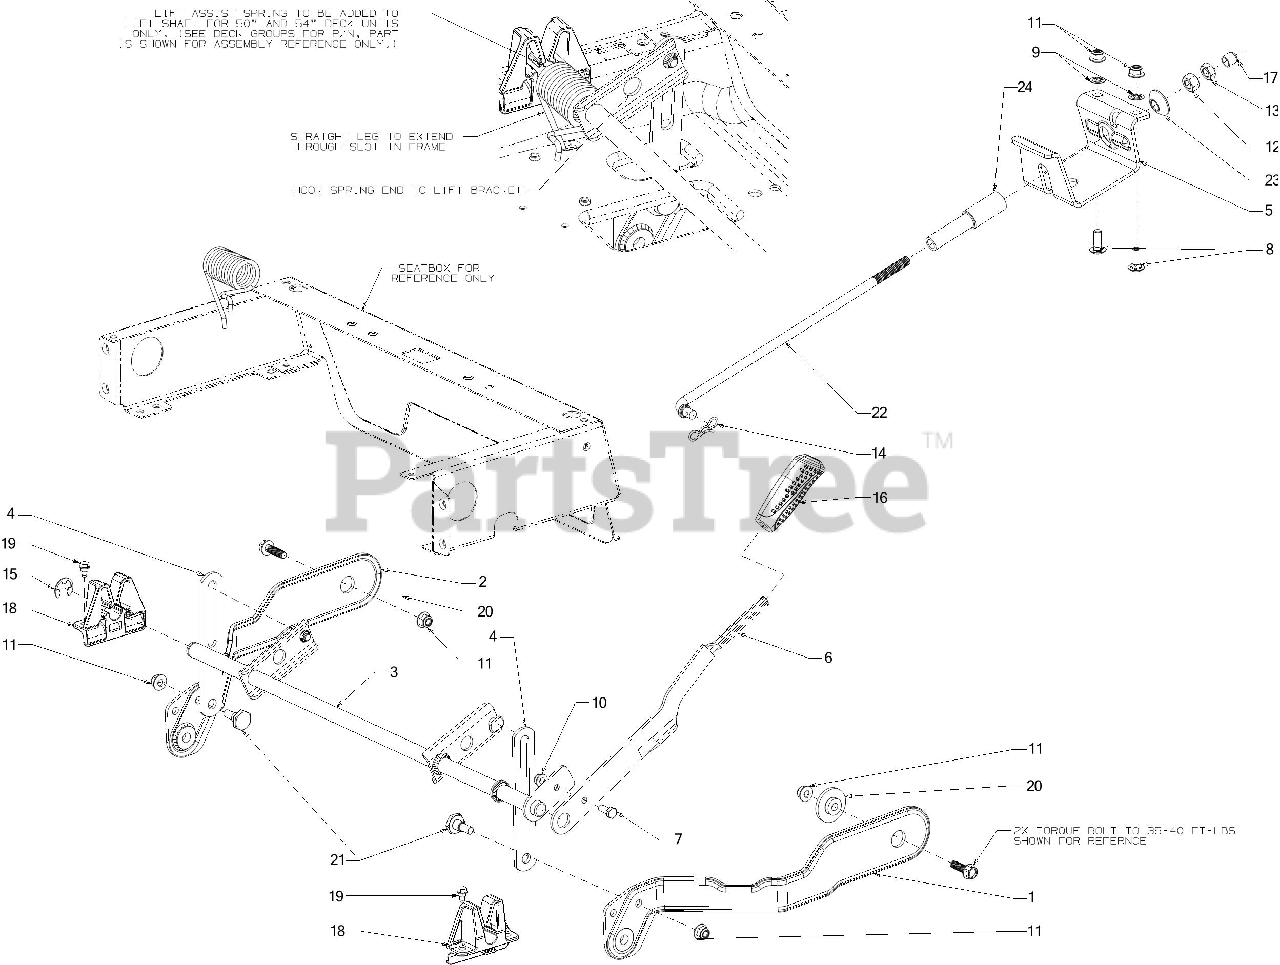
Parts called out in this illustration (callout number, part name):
1	DECK LIFT PLATE ASSEMBLY (RH)
2	DECK LIFT PLATE ASSEMBLY (LH)
3	DECK SHAFT ASSEMBLY
4	LIFT LINK PLATE
5	ROD SUPPORT BRACKET
6	DECK LIFT HANDLE
7	SCREW 5/16-18 x .75 GR5
8	CARRIAGE BOLT 3/8-16 x 1.00 GR5
10	FLANGE LOCK NUT 5/16-18
12	HEX NUT NYLOK 1/2-13
13	HEX NUT
14	BOW TIE COTTER PIN
15	E-RING
17	LIFT ROD END CAP
18	DECK LIFT BRACKET
19	SHOULDER SCREW 1/4-20X.50 19"PSH
20	SHOULDER SPACER -S
21	SHOULDER SCREW
22	DECK FRONT LIFT ROD
23	LIFT PIVOT CUP
24	SLEEVE .55 ID x 4.50 LG
